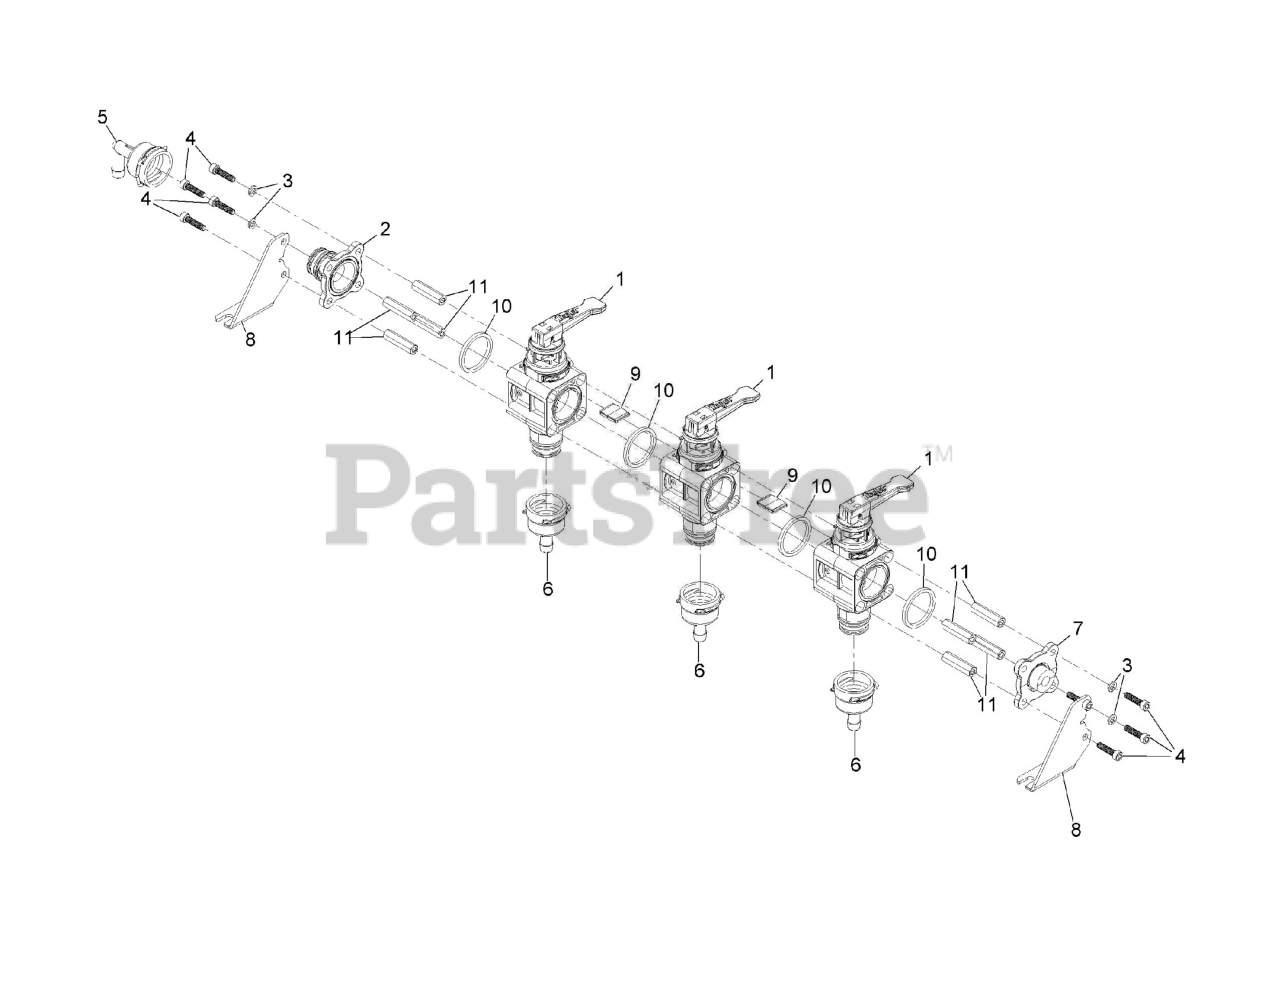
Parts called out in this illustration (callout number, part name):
1	ASM-Valve Section, Grey
2	Adaptor-Male Qc Bolted Flanged
4	Screw-Hscs 6 MM X 25.0 MM SS
5	Kit-Hose Barb, 1/2 90, Qc
6	Kit-1/2 Hb, STR, Qc
8	Brkt-Sprayer Manifold
9	Alignment Piece
11	M6X1 Metric Hex Stand-Off
